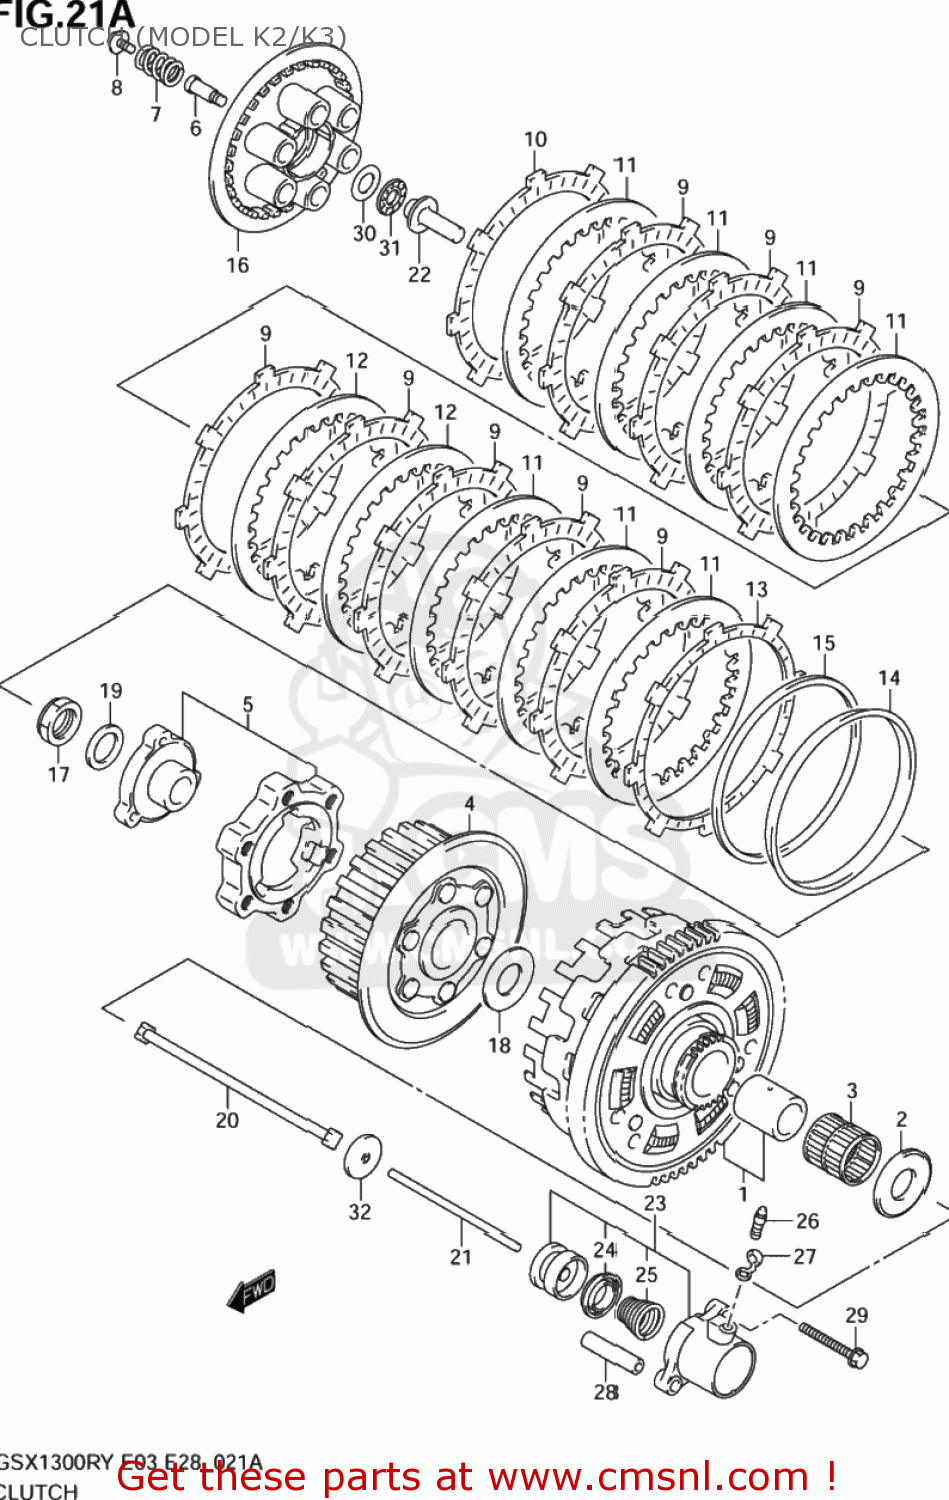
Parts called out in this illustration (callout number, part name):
1	GEAR ASSY,PRI DRIVEN
2	WASHER(25X54X2.5)
3	BEARING(35X40X39.8)
4	HUB,CLUTCH SLEEVE
5	CAM SET,CLUTCH
6	BOLT,CLUTCH SPRING SUPPORT
7	SPRING CLUTCH
8	BOLT,CLUTCH SPRING
9	PLATE,CLUTCH DRIVE NO.1 (NAS)
10	PLATE,CLUTCH DRIVE NO.2 (NAS)
11	PLATE,CLUTCH DRIVEN NO.1(T:2.0 (NAS)
12	PLATE,CLUTCH DRIVEN NO.2(T:2.3 (NAS)
13	PLATE,CLUTCH DRIVE NO.3 (NAS)
14	SEAT,WAVE WASHER
15	WASHER,CLUTCH PLATE WAVE
16	DISC,CLUTCH PRESSURE
17	NUT
18	WASHER(25X50X2.5)
19	WASHER
20	ROD,CLUTCH
21	ROD,CLUTCH PUSH,L
22	PIECE,CLUTCH PUSH
23	CYLINDER,CLUTCH RELEASE
24	CUP
25	SPRING,CLUTCH CYLINDER
26	BLEEDER
27	CAP,BLEEDER
28	PIN
29	BOLT,CL.COVER
30	WASHER(15.5X28X1)
31	BEARING(15X28X2)
32	SEAL,OIL(6X34X5.5)
